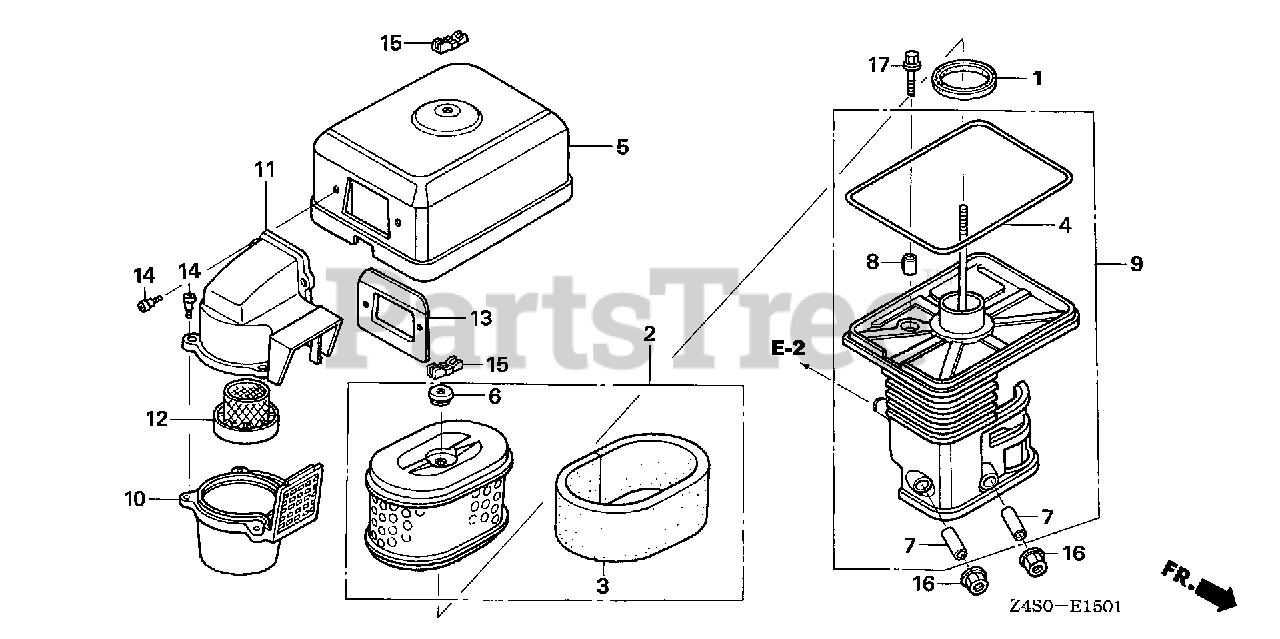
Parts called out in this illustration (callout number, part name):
1	GASKET, ELBOW
2	ELEMENT, AIR CLEANER (DUAL)
3	FILTER (OUTER)
4	GASKET, AIR CLEANER COVER
5	COVER, AIR CLEANER (CYCLONE)
6	GROMMET, AIR CLEANER
7	COLLAR, AIR CLEANER
8	COLLAR B, AIR CLEANER
9	ELBOW, AIR CLEANER
10	CASE, PRE AIR CLEANER
11	CAP, PRE AIR CLEANER
12	GUIDE, PRE AIR CLEANER
13	PLATE, PRE AIR CLEANER
14	BOLT, SPLASH GUARD
15	NUT, TOOL BOX SETTING
16	NUT, FLANGE (6MM)
17	BOLT, FLANGE (6X20)
